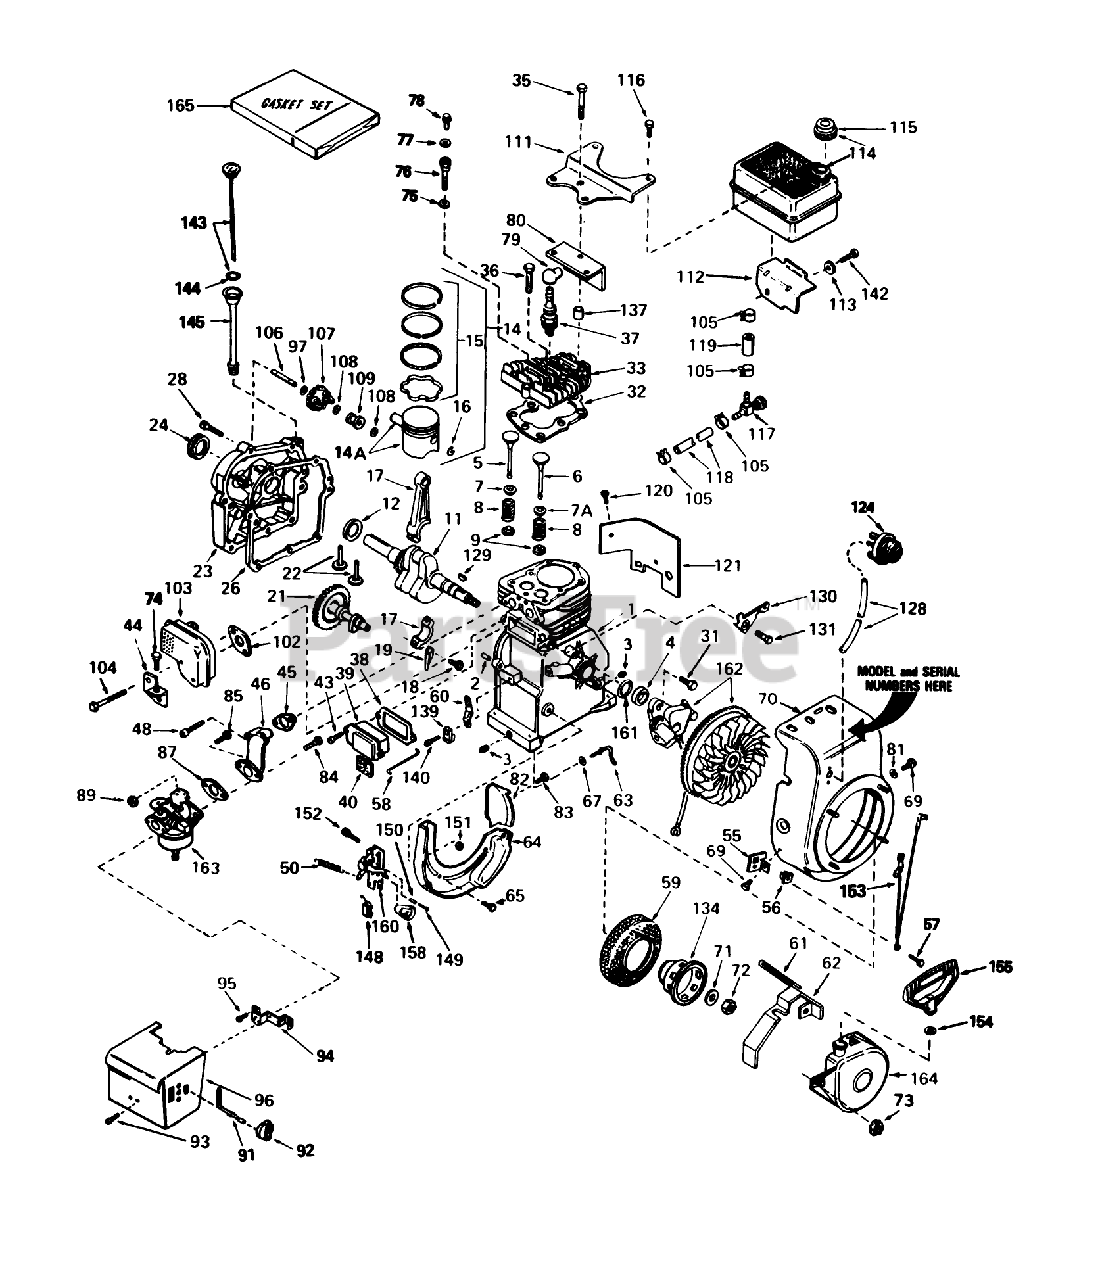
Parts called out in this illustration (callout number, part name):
1	Cylinder Assy. (Incl. Nos.2, 34)
2	Pin-Dowel
3	Plug-Drain, Oil (SQH 1/4-18)
4	Seal-Oil
5	Valve-Intake Standard (Incl. Ref. #151)
5	Valve-Intake 1/32" oversize (Incl. Ref. #151)
6	Valve, Exhaust (Std.)(Incl. No. 40)
6	Valve, Intake (1/32" oversize)(Incl. No. 40)
7	Cap-Upper Valve Spring
7A	Cap, Upper Valve Spg (Exhaust)
8	Spring-Valve
9	Cap-Valve, Spring
11	Crankshaft ASM
12	Washer-Thrust
14	Piston, Pin Ring Assy., (Incl. Ref. #15 16) (Std.)
14	Piston, Pin Ring Assy., (Incl. Ref. #15 16) (.010 Oversize)
14	Piston, Pin Ring Assy., (Incl. Ref. #15 16) (.020 Oversize)
14A	Piston Pin Assy. (Incl. Ref. #16) (Std.)
14A	Piston Pin Assy., (Incl. Ref. #16) (.010 Oversize)
14A	Piston Pin Assy. (Incl. Ref. #16) (.020 Oversize)
15	Ring Set-Piston Std.
15	Ring Set-Piston .010 oversize
15	Ring Set-Piston .020 oversize
16	Ring-Retaining, Piston Pin
17	Rod Assy., Connecting (Incl. Nos. 18 19)
18	Bolt-Rod, Connecting
19	Dipper-Oil
21	Camshaft
22	Lifter-Valve
23	Cover, Cylinder (Incl. Ref. #24 106)
24	Seal-Oil
26	Gasket-Cylinder Cover
28	Screw (1/4-20 x 1-1/4)
31	Screw
32	Oil Fill Tube
33	Head Cylinder
35	Screw (5/16-18 X 2)
36	Screw (5/16-18x1-1/2)
37	Plug, Spark (J17LM or equiv.)
37	Plug, Spark (Champion RCJ-8)
38	Gasket Breather
39	Breather Assembly (Incl. Nos. 52 84)
40	Element-Breather
43	Screw
44	Bracket-Cover, Carburetor
45	Gasket-Intake
46	Pipe-Intake
48	Screw (1/4-20 x 1-19/32)
50	Spring-Extension
55	Bracket
56	Grommet
57	Screw
58	Link-Governor to Throttle
59	Screen-Starter
60	Lever-Governor
61	Seal, Snowguard
62	Guard-Starter
63	Rod-Governor
64	Baffle-Blower Housing
65	Screw (1/4-20x19/32)
67	Washer-Flat
69	Screw
70	Housing-Blower
71	Washer-Belleville
72	Nut-Flywheel
73	Nut and Lock Washer (1/4-28)
74	Screw (10-24 x 3/8)
75	Washer-Flat
76	Screw ( 5/16-18 x 1-1/2)
77	Washer
78	Screw
79	Cover-Spark Plug
80	Baffle-Heat
81	Washer
82	Baffle-Extension
83	Screw-Hex Washer Hd.
85	Screw-Fil. Hd.
87	Gasket
89	Nut and Lock Washer (1/4-28)
91	Rod-Choke
92	Knob-Control
93	Screw (8-32 X 5/16)
94	Bracket-Choke
95	Screw (10-32 x 1/2)
96	Cover-Carburetor
97	Washer-Flat
102	Gasket-Exhaust
103	Muffler
104	Screw-Fil. Hd.
105	Clamp-Line, Fuel
106	Shaft-Governor
107	Governor Gear ASM
108	Ring-Retaining
109	Spool-Governor
111	Plate-Fuel Tank
112	Bracket-Fuel Tank
113	Washer
114	481-1261 SENATOR TI
115	Cap, Fuel
116	Screw (1/4-15x7/8)
117	Valve-Shut Off
118	Line-Fuel
119	Line-Fuel (8.62)
120	Screw
121	Extension-Blower
124	Primer Assy.
128	Line-Primer
129	Key-Flywheel
130	Bracket-Hold Down
131	Screw (10-24 x 9/16)
134	Cup-Starter
137	pacer
139	Clamp-Lever, Governor
140	Screw
142	Screw Assembly
143	Dipstick
144	O-Ring
145	Tube Fill
148	Terminal
149	Screw
150	Spring-Compression
151	Nut-Lock
152	Screw
153	Wire-Ground
154	Washer
155	Handle-Starter, Mitten Grip
158	Knob-Control
160	Control Assembly, Speed (Incl. Ref. #155 thru 158 160)
161	Gasket Stator
162	Magneto (The complete magneto in not available as an assembly. The magneto number is shown for reference purposes only. Order component parts individually, as shown in parts list)
163	Carburetor (Incl. Ref. #87)
164	Starter Assy.-Rewind
165	Gasket Set
